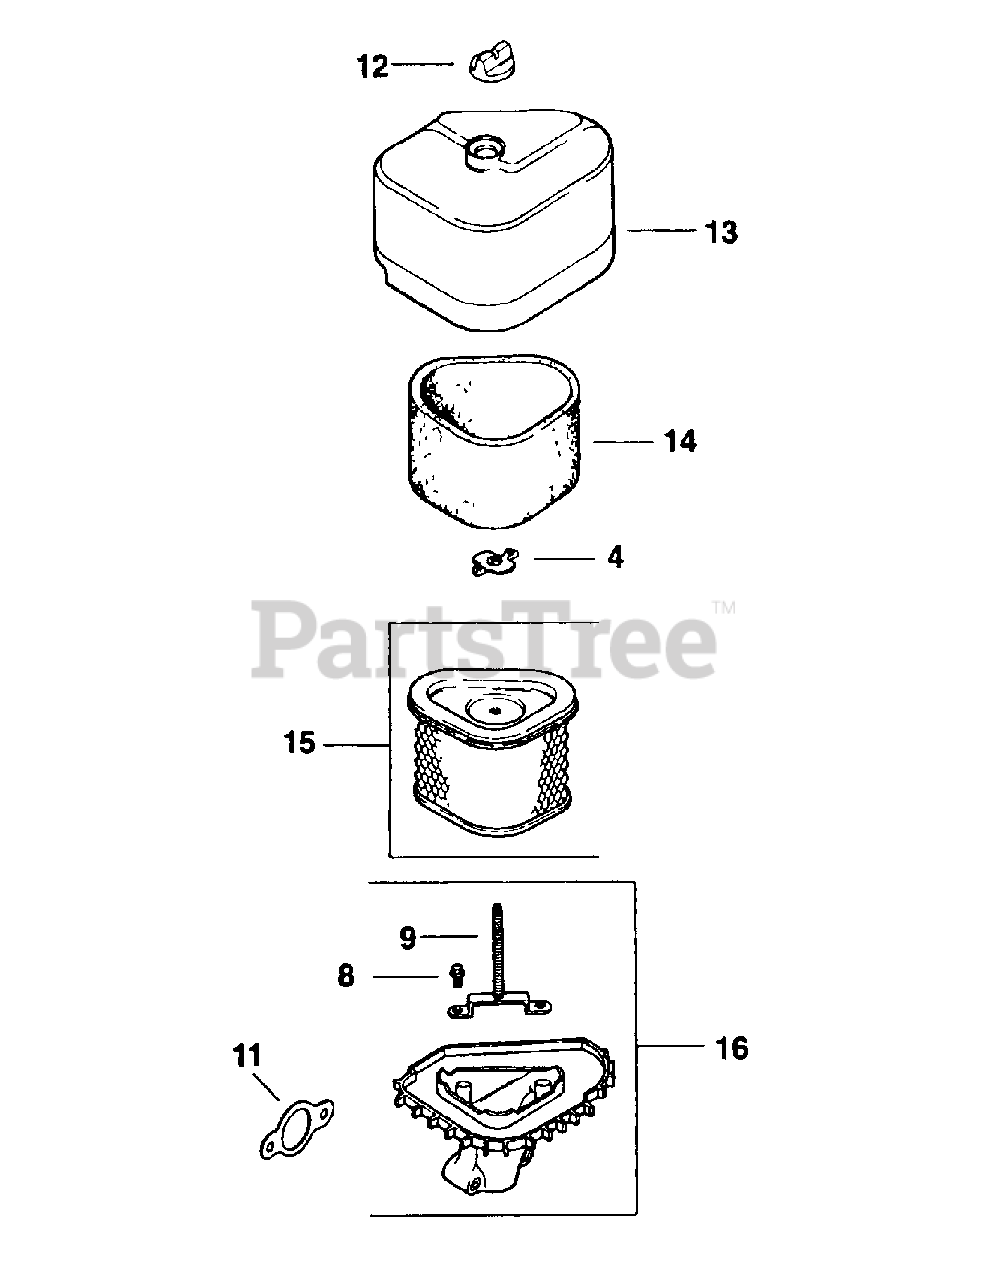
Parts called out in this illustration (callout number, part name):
4	Nut, Wing
8	Screw, Hex Cap #10 Hi-Lo
9	Stud, Mounting Plate
11	Gasket, Air Cleaner
12	Knob, Air Cleaner Cover
13	Cover, Air Cleaner
14	Precleaner
15	Element, Air Cleaner
16	Base, Air Cleaner
